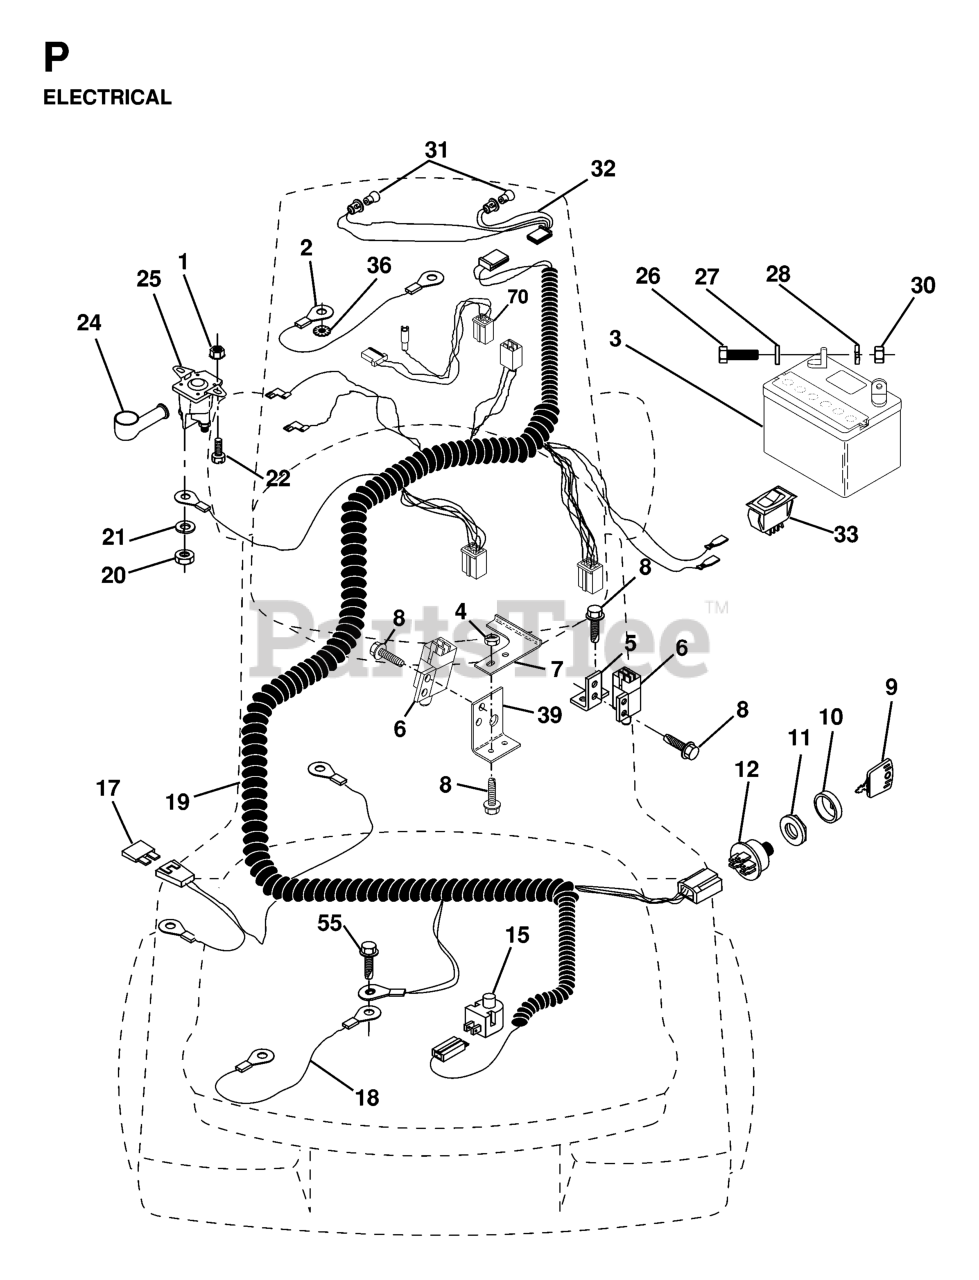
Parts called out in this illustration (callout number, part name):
1	Nut, Keps Blk Hex 1/4-20 UNC
2	CABLE.BATTERY.6GA.16"RED
3	REPL BY 532 12 38-99
5	BRACKET LT
6	SWITCH INTERLOCKT
7	KEEPER, ACTUAT. L.R.
9	KEY MLD GEN DELTA
10	COVER SWITCH KEY
11	NUT, IGNITION
12	IGNITION SWITCH
15	RP.SWITCH.PLUNGER.NC.GRAY
18	CABLE ASSY
19	HARNESS IGN LR NLA
20	NUT
21	LOCKWASHER
22	BOLT
24	TERMINAL COVER
25	SOLINOID
26	BOLT.HEX.1/4.X.3/4.DICHROMATE
28	LOCKWASHER
30	NUT
32	HARNESS HEADLIGHT
36	Washer, Lock, Internal Tooth 1/4
55	Screw 5/16-18 x 1/2 Hex, Self Tapping 5/16-18 x 1/2
70	HARNESS, ENGINE
